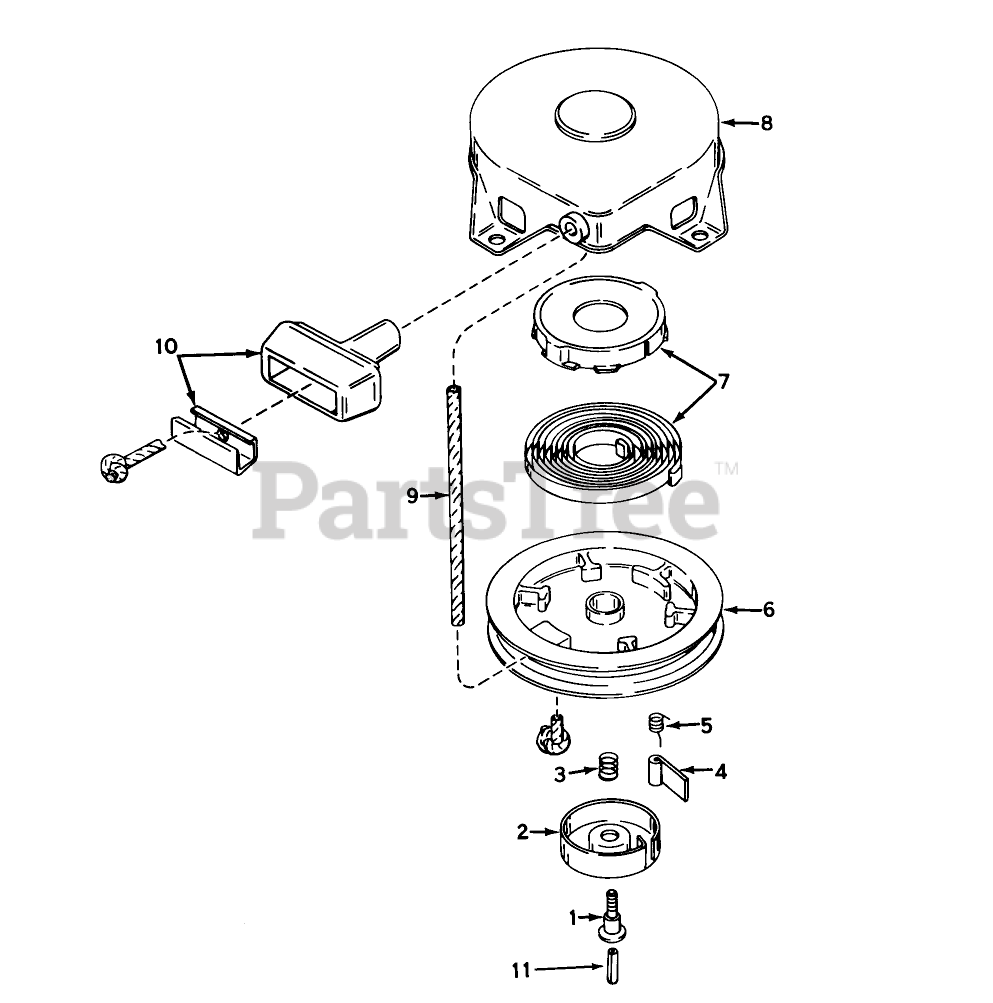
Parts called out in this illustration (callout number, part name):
1	Screw
2	Retainer
3	Spring-Brake
4	Dog-Starter
5	Spring-Dog
7	Spring & Keeper Assy
8	STARTER HOUSING ASSY
9	Rope Starter
10	Assy., Starter
11	Centering
